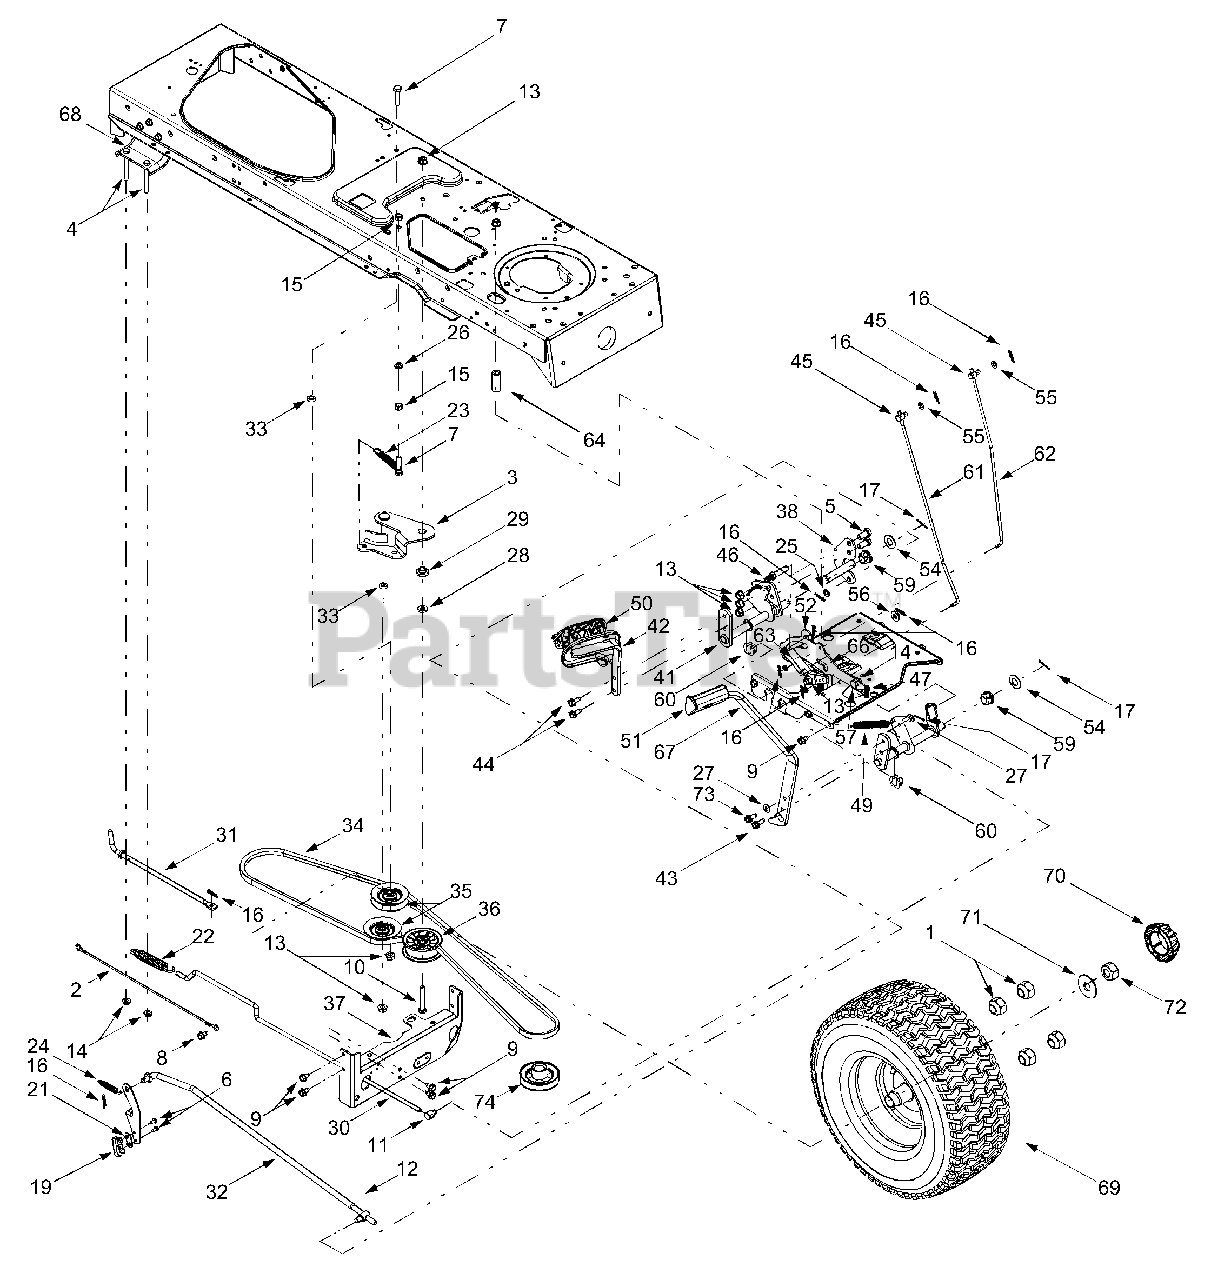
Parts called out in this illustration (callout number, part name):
1	Lug Nut, 3/4-16
2	Reverse/Ground Wire Harness Adapt
3	Double Idler Bracket Assembly
4	Hex Cap Screw, 5/16-18 x 2.75
5	Hex Cap Screw, 3/8-16 x .75
6	Screw, #8-18 x .5
7	Hex Cap Screw, 3/8-16 x 1.5
8	Self-tapping Screw, 1/4-20 x .50
9	Self-tapping Screw, 5/16-18 x .625
10	Hex Cap Screw, 3/8-16 x 2.25
11	Ferrule, 5/16-18
12	Ferrule, 3/8-24
13	Flange Lock Nut, 3/8-16
14	Flange Lock Nut, 5/16-18
15	Hex Nut, 3/8-16
16	Internal Cotter Pin
17	Cotter Pin
18	Cable Tie
19	Short Spring Switch
20	Push-mount Cable Tie
21	Insulator Nut Plate
22	Extension Spring, .59 x 4.0
23	Extension Spring, .5 x 3.97
24	Extension Spring, 3/8 x 1.44
25	Flat Washer, .385 x .62 x .063
26	Lock Washer, 3/8
27	Flat Washer, .344 x .750 x .120
28	Flat Washer, .407 x .812 x .135
29	Shoulder Spacer, .38
30	Hydrostatic Control Rod
31	Hydrostatic Bypass Rod
32	Hydrostatic Brake Rod
33	Spacer, .376 x .625 x .22
34	Drive Belt
35	V-idler Pulley, 3.06
36	Flat Idler Pulley, 2.75
42	Hydro Pedal Assembly
43	Self-tapping Screw, 5/16-18 x .875
44	Self-tapping Screw, 5/16-18 x .75
45	Ferrule, 1/4-20
46	Pin, 3/8-16 x 2.43
47	Compression Spring, .40 OD x 1.17
48	Extension Spring, .50 OD x 1.41
49	Extension Spring, .50 OD x 6.37
50	Drive Pedal Pad
51	Brake Pedal Pad
52	Flat Washer, .411 x 1.25 x 1.0
53	Flat Washer, .281 x .50 x .063
54	Flat Washer, .64 x 1.24 x .06
55	Flat Washer, .344 x .062 x .03
56	Flat Washer, .406 x .875 x .105
57	Shoulder Screw, .437 x 1.62
58	Shoulder Screw, .5 x .434
59	Hex Flange Bearing
60	Split Hex Flange Bearing
61	Cruise Control Rod
62	Brake Lock Control Rod
63	Cruise Latch
64	Spacer, 5/16 x 1.54
66	Drive Lockout Bracket
70	Hub Cap
71	Flat Washer, .780 x 1.59 x .062
72	Jam Nut, 3/4-16
73	Self-tapping Screw, 5/16-18 x .75
74	Engine Pulley
